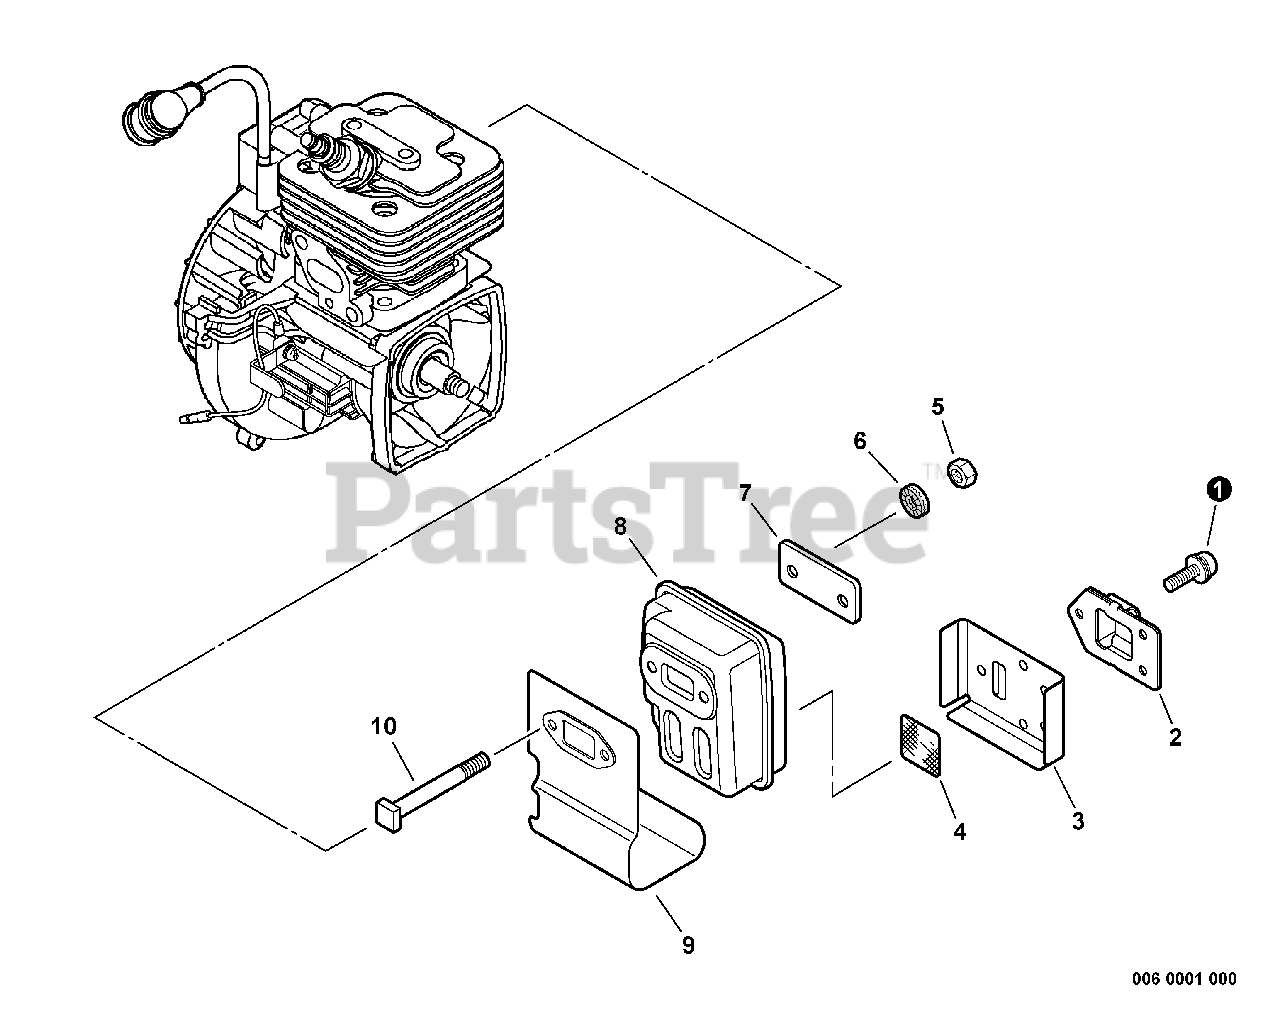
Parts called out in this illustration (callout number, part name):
1	SCREW - 4X12
2	GUIDE, EXHAUST
3	GASKET, EXHAUST
4	SCREEN, SPARK ARRESTOR
6	LOCKWASHER
8	MUFFLER
9	SHIELD, EXHAUST
